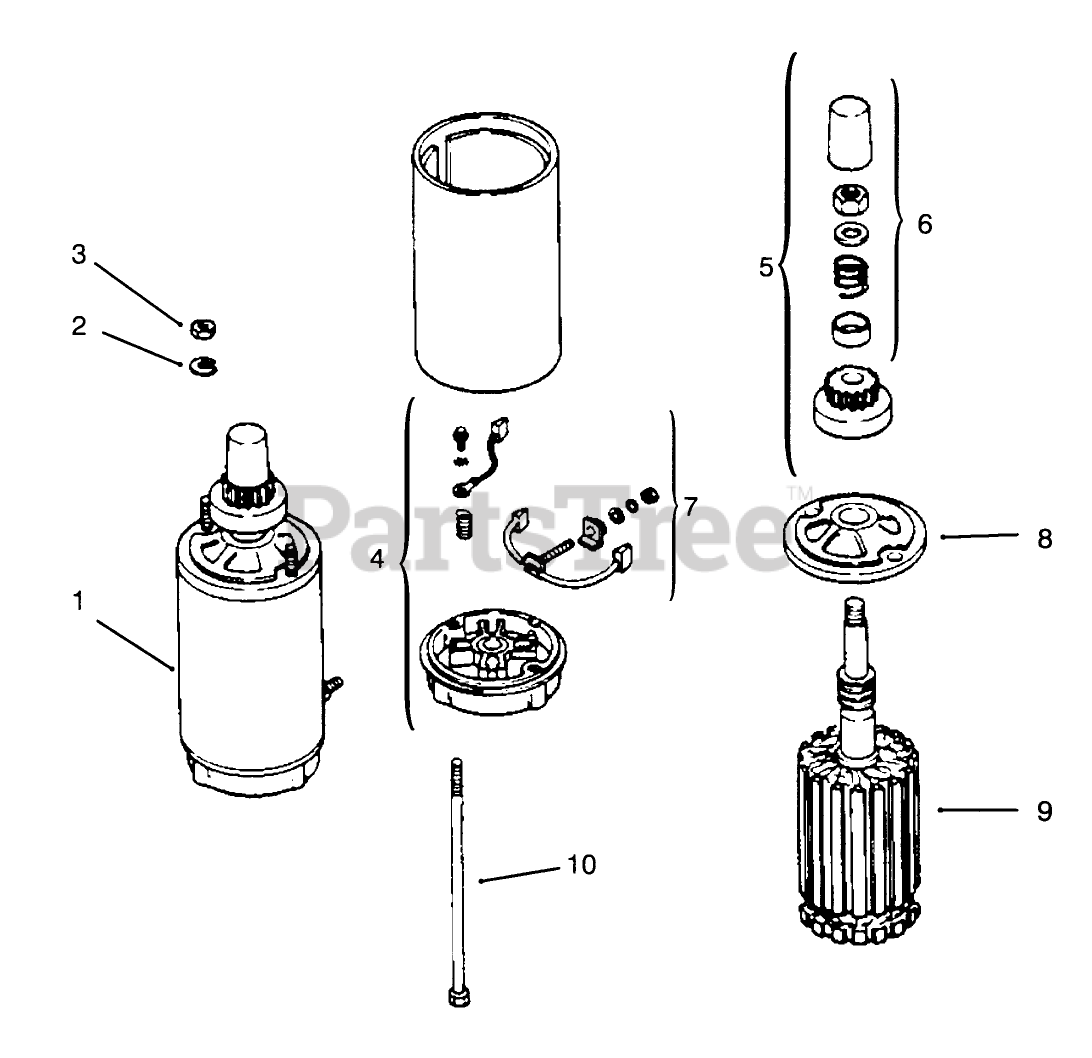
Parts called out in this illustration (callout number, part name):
1	Starter Assembly (Incl. Ref. #4-10)
2	Washer
4	Cap-Commutator End
5	Kit-Drive
6	Kit-Drive Parts
7	Kit-Brush
8	Cap-Drive End
9	ARmature
